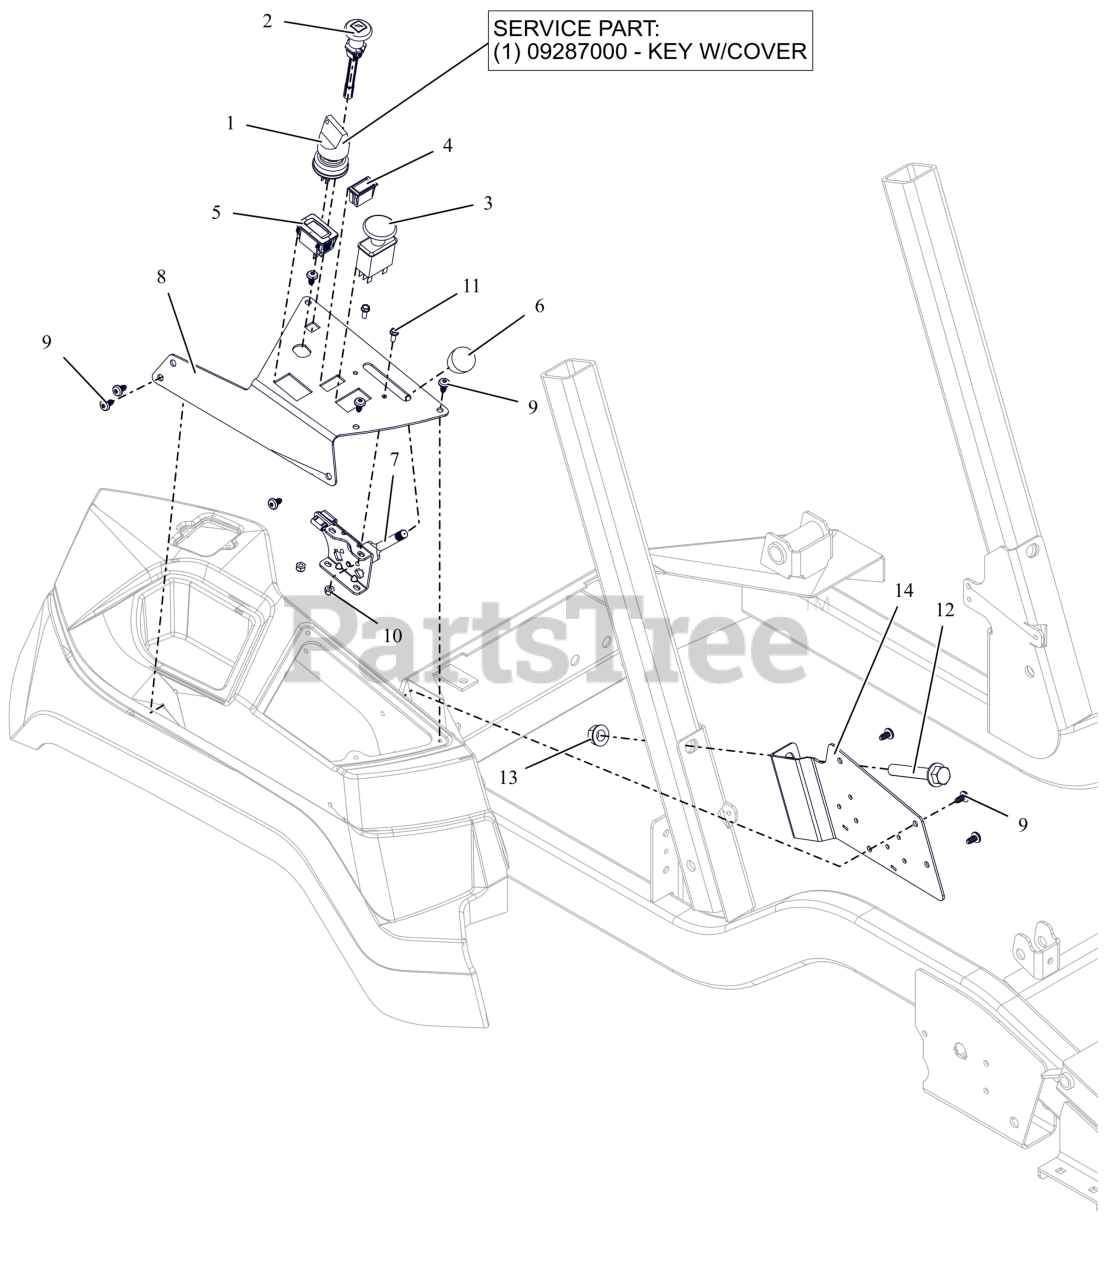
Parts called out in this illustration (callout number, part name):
1	SWITCH, IGNITION
1	KEY, W/ SHIELD
2	CABLE - CHOKE, SNAP-IN
3	SWITCH, CLUTCH
4	SWITCH,BLANK
5	HOUR METER
6	KNOB-CONTROL-BLACK .38-16X.50
7	CABLE, PRO THROTTLE CONTROL
8	PLATE, APEX CONTROL PANEL
9	SCR-PAN .25-15X.50 6L H/LZB500
10	NUT-LK-NYL #10-24 G2 ZCC
11	BLT, HWH #10-24X.50 ZCC
12	BLT- HEX-FLG .50-13X3.00 G5 ZC
13	NUT-LK-CTR-FLG .500-13 GG ZCC
14	BRKT, FENDER/RELAY MOUNTING
